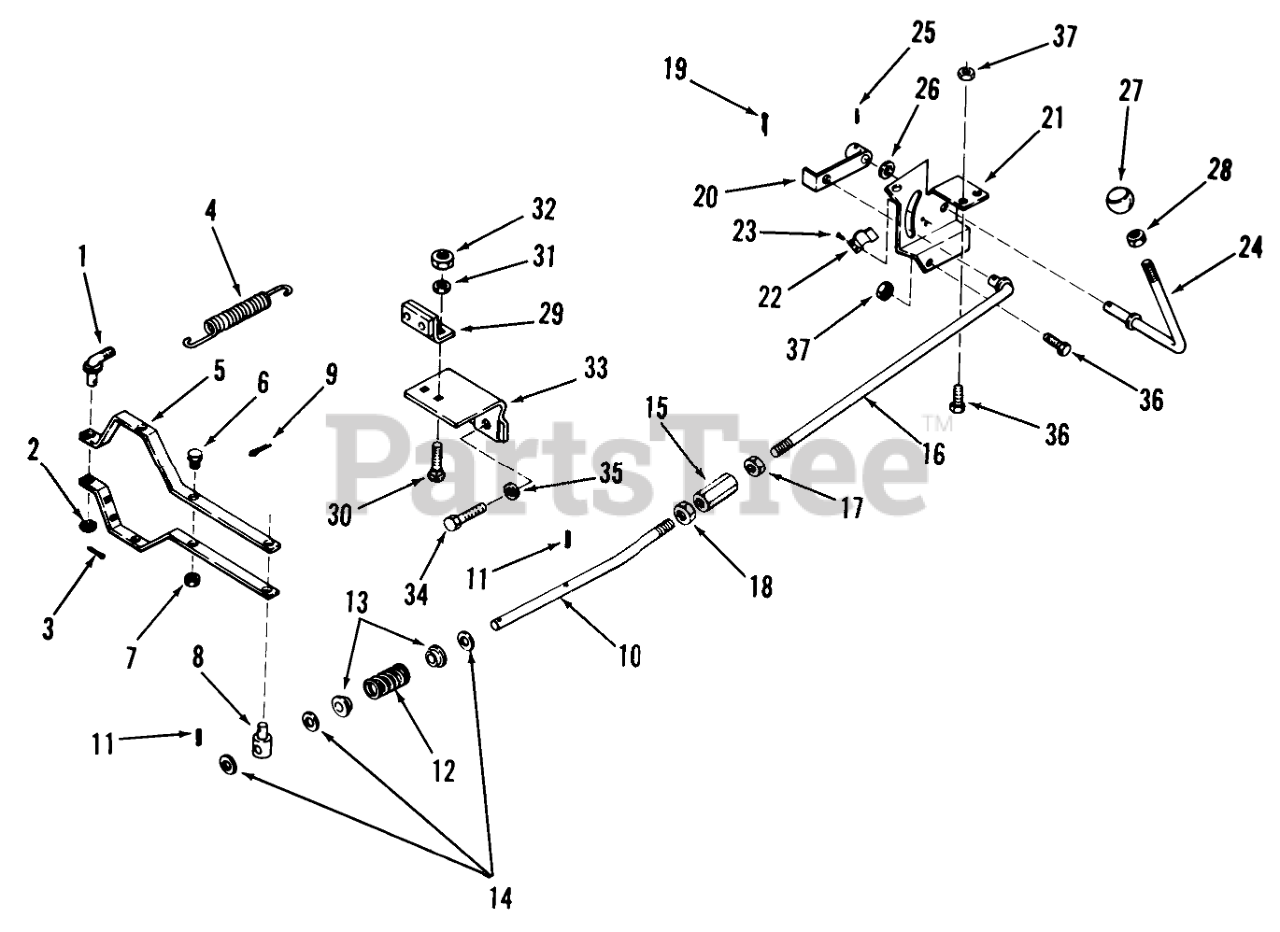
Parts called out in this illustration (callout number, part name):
1	ASSY HOOK
2	WASHER
3	Pop Rivet
4	CLUTCH SPRING
5	ASSY-CLUTCH BAR R
6	BOLT
7	Nut
8	TRUNION
10	CLUTCH ROD
11	PIN-ROLL
12	SPRING
13	BUSHING
14	Washer
15	TURN BUCKLE NUT
16	Assy-Clutch Rod
17	Jam Nut
20	ARM CLUTCH ENGAGE
21	BRACKET
22	Clip Spring
23	RIVET -4
24	ASSY CLUTCH HANDLE
25	Spirol Pin
26	Washer
28	Jam Nut
29	Clutch Brake
30	Bolt 1/4-20 X 5/8
32	Nut
33	Bracket-Brake
35	LOCKWASHER
36	Bolt
37	Nut
